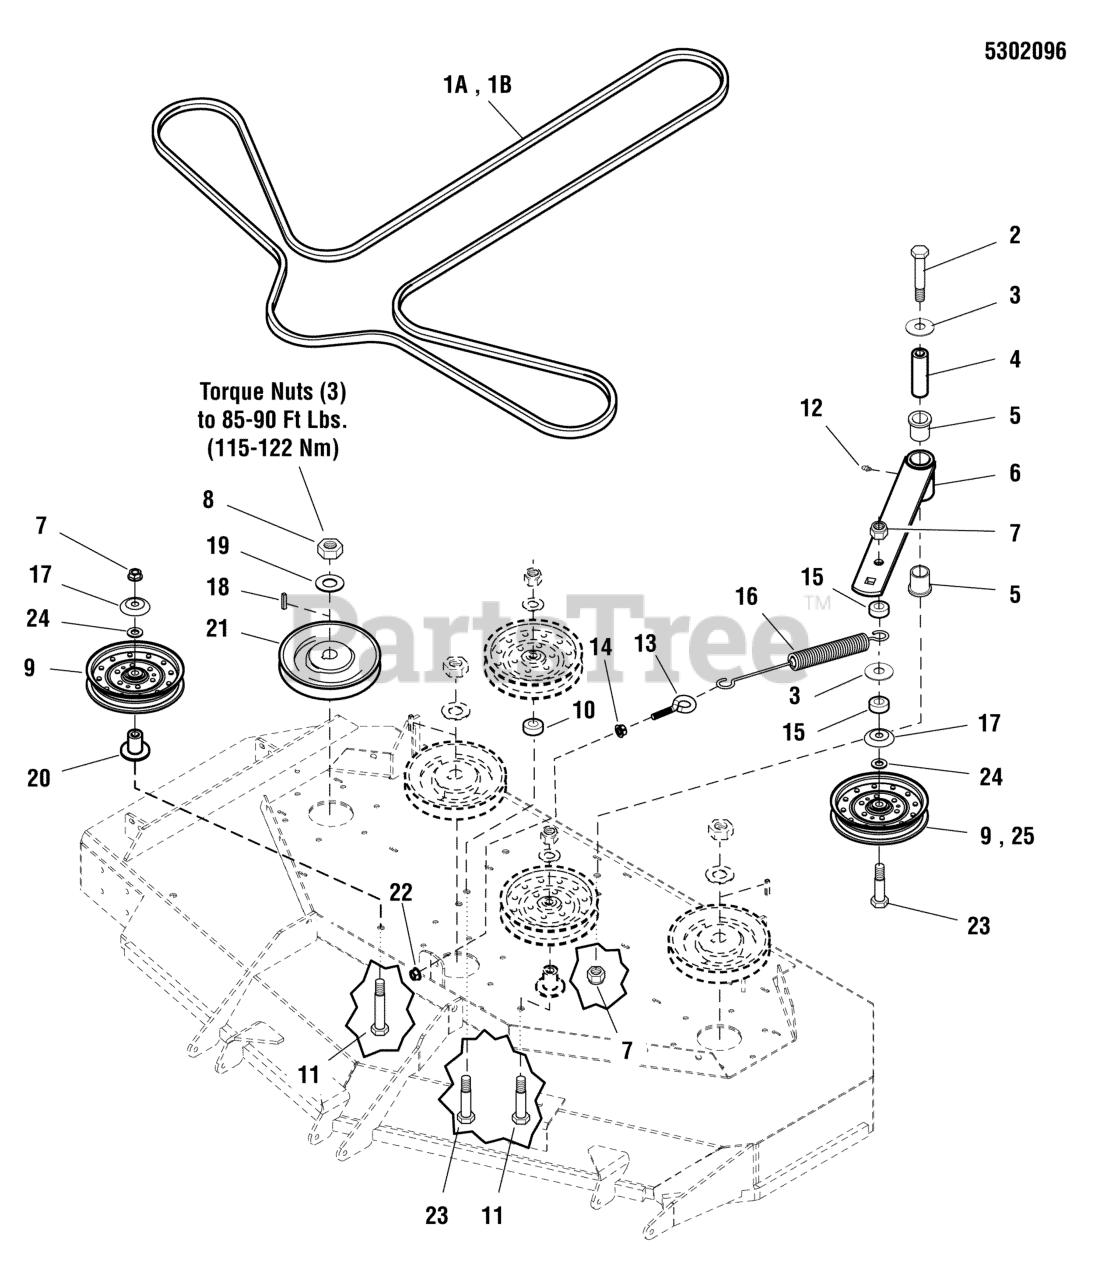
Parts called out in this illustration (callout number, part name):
2	BOLT, 1/2-13 X 4-1/2 GD5 YZ
3	WASHER, 1/2 USS
4	SPACER, .52 X 1.00 X 3.5
5	BUSHING, FLANGE
6	WELD, IDLER ARM - BLK
7	NUT, Hex Flange, Nylock, 1/2-13
8	NUT, 3/4-16 HEX
10	SPACER, .51 X 1.75 X .75
11	BOLT, 1/2-13 X 3" GD5 CZ
12	GREASE FITTING, 1/4-28 STRAIGHT
13	EYE BOLT, 3/8-16 X 5, 2.88THRD, 1EYE, CZ
14	NUT, 3/8-16 HEX JAM
15	SPACER, .52 X 1.00 X .44, CZ
16	SPRING-EXTENSION, SWIVEL END
17	SHIELD, PULLEY BEARING
18	KEY, 1/4 SQ X 1-1/4
19	WASHER, 3/4 BELLEVILLE
20	IDLER MOUNT
21	PULLEY, 6.93 EOD X 25MM, SPLIT
22	NUT, 3/8-16 HEX NYLOCK FLANGE
23	BOLT, 1/2-13 X 2-3/4 GD5 CZ
24	WASHER, 1/2 SAE
